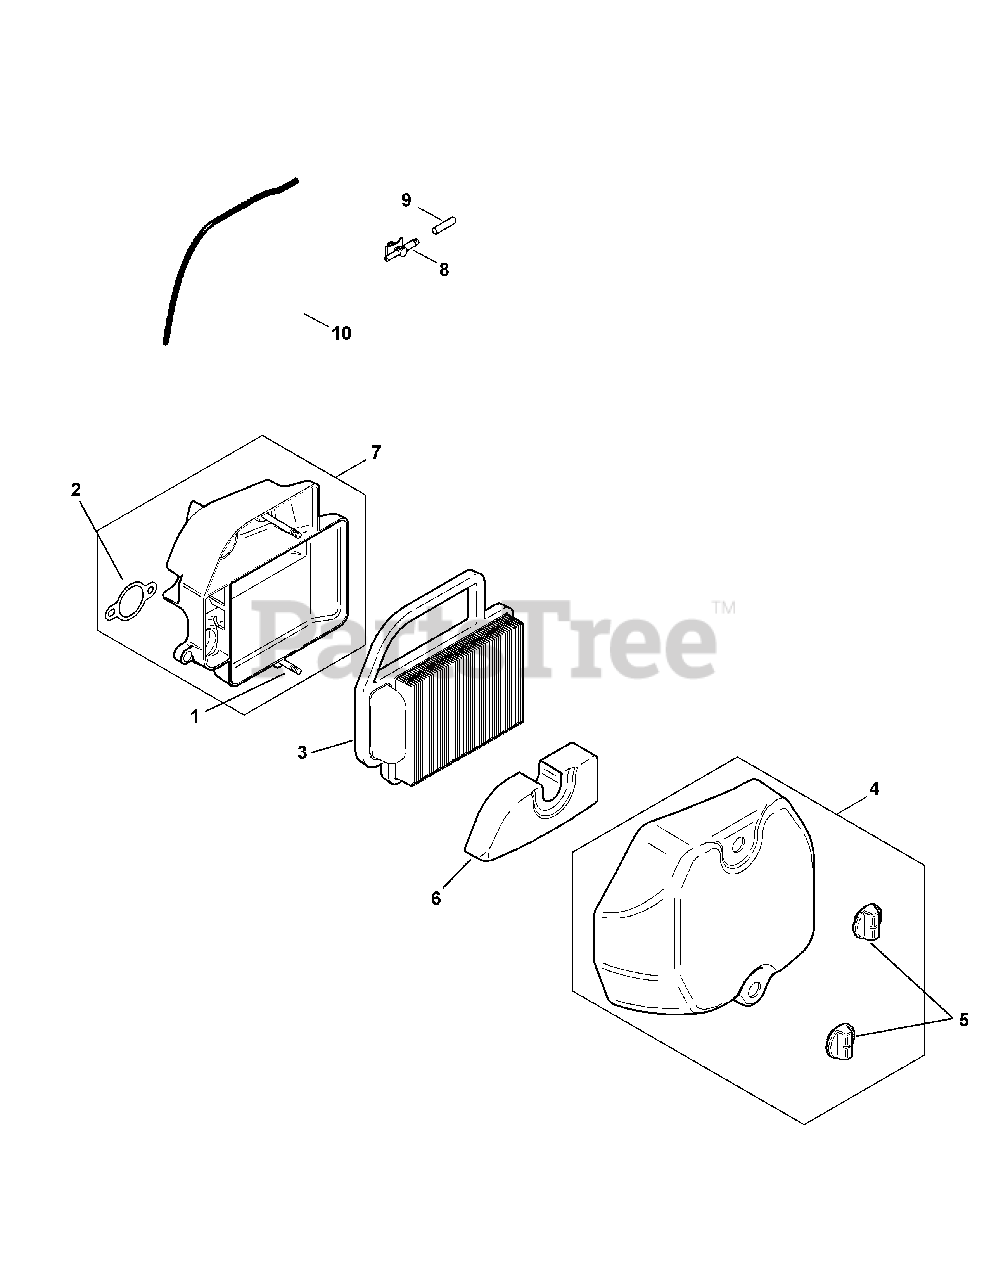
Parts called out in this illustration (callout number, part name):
1	Air Cleaner Base Stud
2	Air Cleaner Base Gasket
3	Air & Pre Cleaner Elements
4	Air Cleaner Cover Kit
6	Pre-Cleaner Element (Dry)
7	Air Cleaner Base Kit
8	Evaporative Connector
10	Hose, Evaporative, 20"
